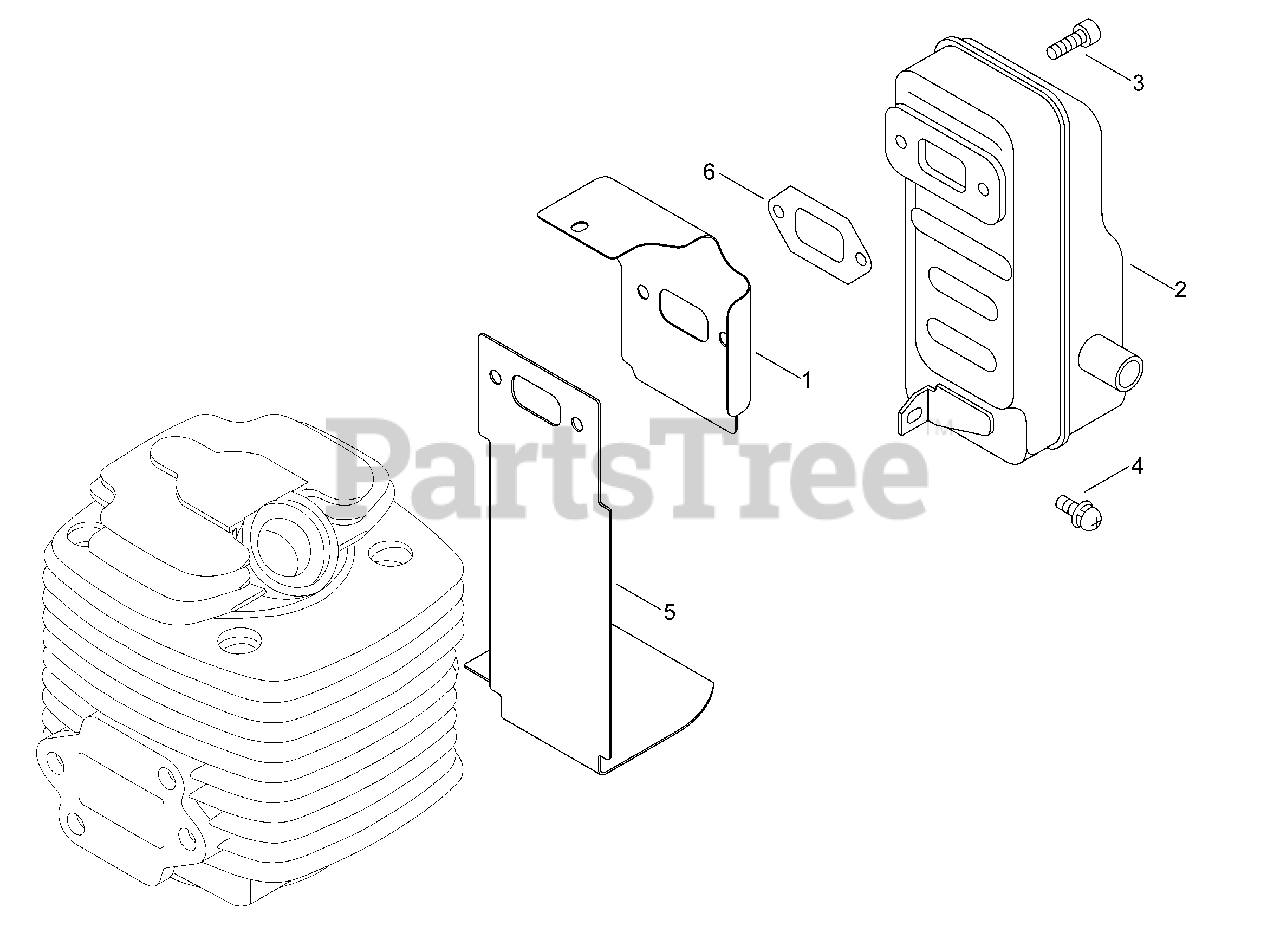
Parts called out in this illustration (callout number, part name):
1	COVER, ENGINE - EXHAUST
2	MUFFLER ASSY
3	BOLT 6×20
4	SCREW 5×14
5	HEAT SHIELD, EXHAUST
6	GASKET, MUFFLER
